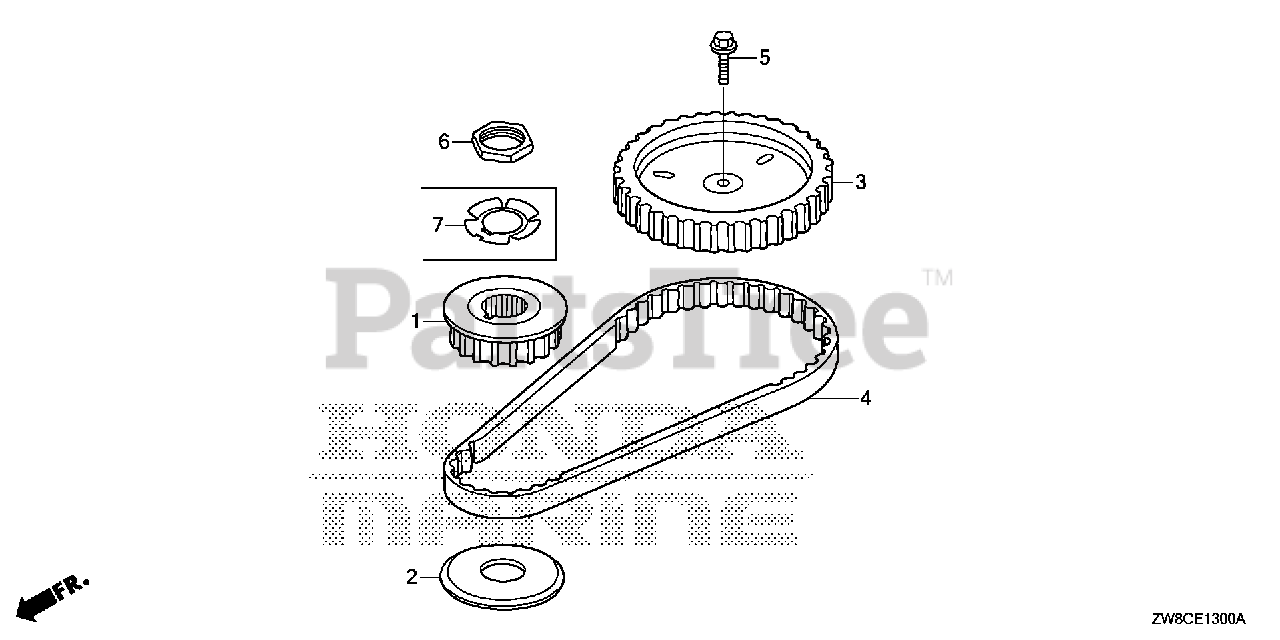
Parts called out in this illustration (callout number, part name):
1	PULLEY, TIMING
2	FLANGE, TIMING PULLEY
3	PULLEY, CAMSHAFT
4	BELT, TIMING (63RU13 B-333)
5	BOLT, FLANGE (6X20)
6	NUT, LOCK (24MM)
7	WASHER, LOCK (24MM)
